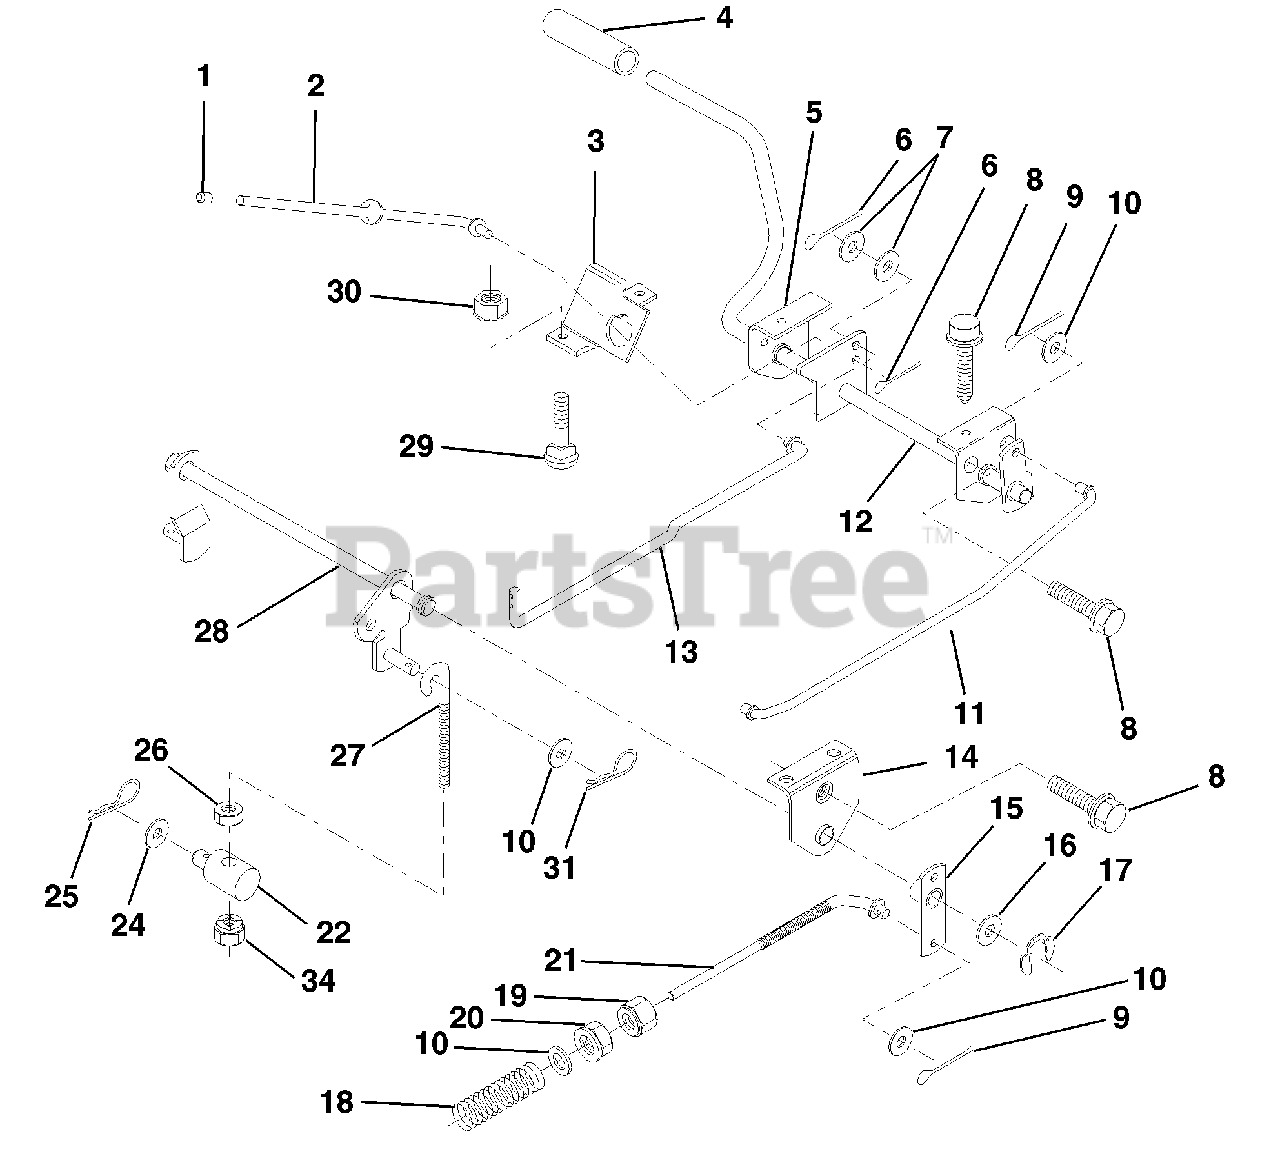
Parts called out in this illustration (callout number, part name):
1	Cap, Plunger
2	Rod, Parking Brake
3	Bracket, Parking Brake
4	Cover, Pedal
5	Bracket, Clutch/Brake Pedal, L.H.
6	Pin, Cotter 3/32 x 3/4
7	Washer 13/32 x 5/8 x 16 Ga.
8	Screw, Hex, Thd. Roll. 5/16-18 x 1/2
9	Pin, Cotter 1/8 x 3/4
10	Washer 13/32 x 13/16 x 16 Ga.
11	Rod, Brake Front
12	Assembly, Clutch/Brake Pedal
13	Rod, Clutch
14	Bracket, Lift, Shaft
15	Assembly, Brake, Pivot, Arm
16	Washer 25/32 x 1-1/8 x 16 Ga.
17	Ring, Klip
18	Spring, Brake Rod
19	Nut, Hex, Jam 3/8-16 UNC
20	Nut, Lock, hex. w/Ins. 3/8-16 INC
21	Rod, Rear Brake
22	Trunnion, Lift
24	Washer 13/32 x 1-1/4 x 12 Ga.
25	Spring, Retainer
26	Nut, Centerlock 3/8-16 UNC
27	Link, Threaded
28	Assembly, Rear Mower Lift
29	Bolt, Carriage 5/16-18 UNC x 3/4
30	Nut, Keps 5/16-16 UNC
31	Retainer Spring
34	Nut, Crownlock 3/8-16 UNC
